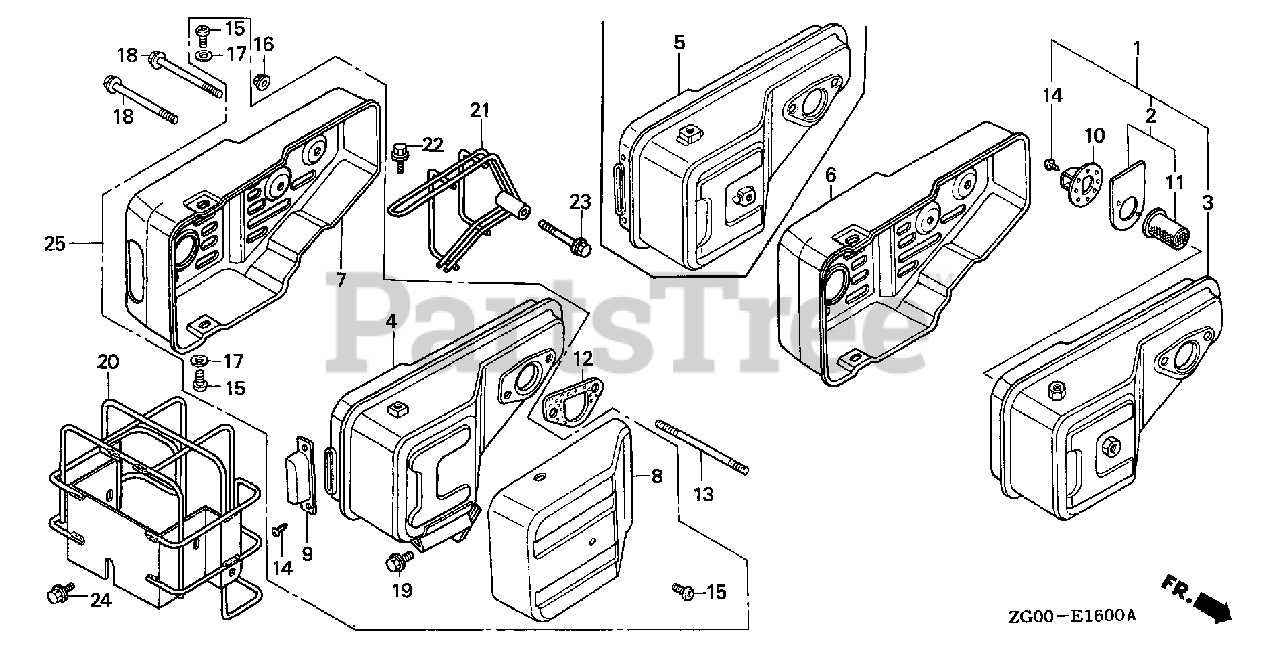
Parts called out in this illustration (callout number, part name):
3	MUFFLER (W/PROTECTOR)
6	PROTECTOR, MUFFLER
8	SEPARATOR, MUFFLER
10	DEFLECTOR, MUFFLER
12	GASKET, MUFFLER
13	BOLT, STUD (6X50)
14	SCREW, TAPPING (4X8)
15	SCREW, PAN (6X6)
16	NUT, FLANGE (6MM)
